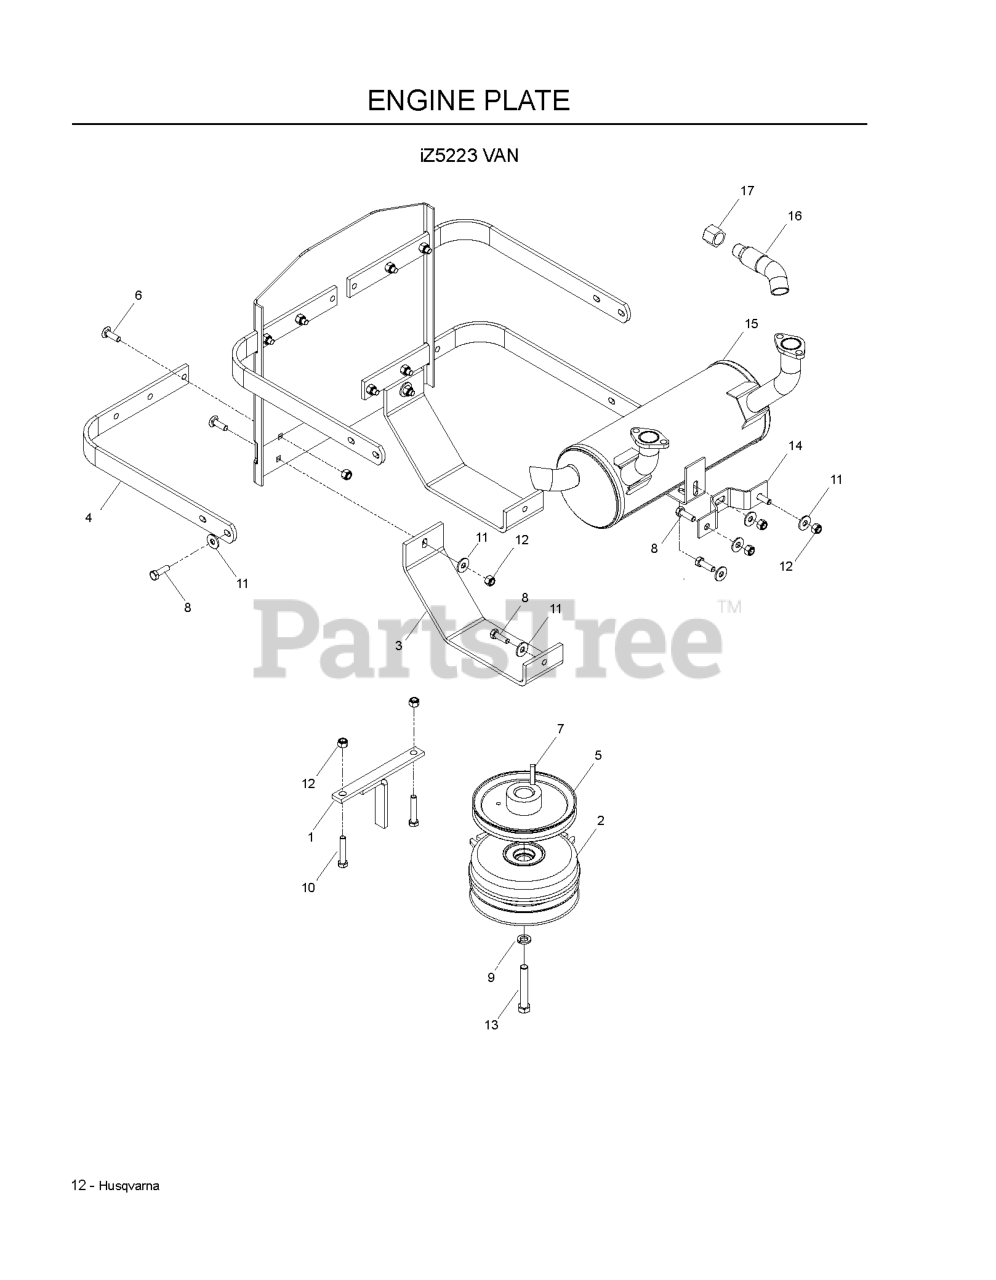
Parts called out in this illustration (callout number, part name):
1	CLUTCH TIE DOWN
2	CLUTCH-200 FT LB(RPLS 5218-102
3	SKID PLATE
4	ENGINE SHROUD BRKT
6	RHSSNB 5/16C X 1.0
7	KEY, 1/4 SQ X 1 1/4
8	HCS 5/16C X 1
9	WASHER 7/16 LOCK
10	HCS 5/16C X 1 3/4
11	WASHER 5/16 FLAT
12	NUT 5/16 NYLOC
13	HCS 7/16-20 X 2-3/4
14	BRACKET, MUFFLER
15	MUFFLER VANGUARD 23HP
16	OIL DRAIN HOSE
